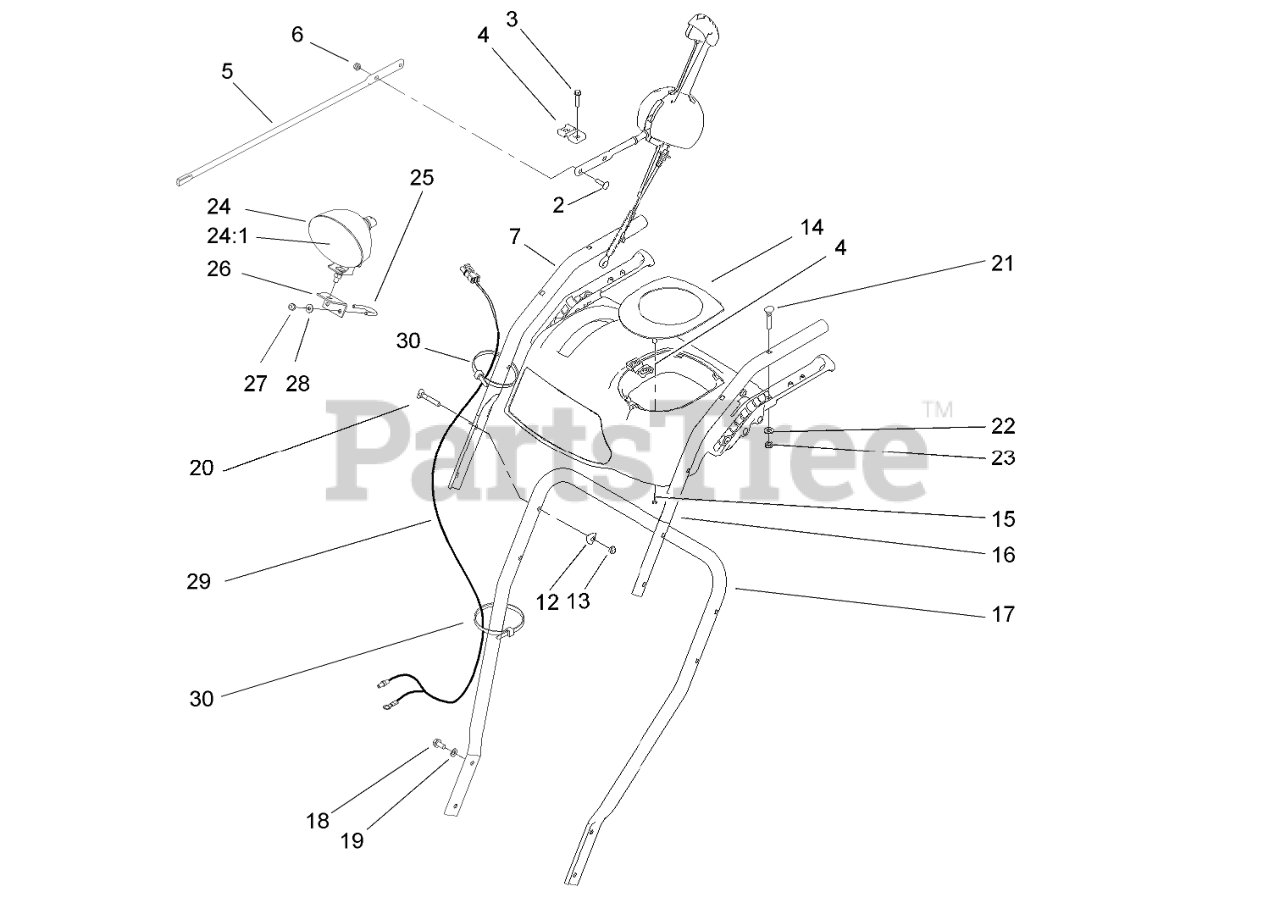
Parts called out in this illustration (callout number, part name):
2	SCREW-CARR
3	SCREW-PLASTITE
4	SUPPORT-ROD
5	ROD-CHUTE, FRONT
6	NUT-LOCK, NI
7	HANDLE-UPPER, RH
12	WASHER
13	NUT-LOCK, NI
14	COVER-PANEL, CONTROL
15	SCREW-PPH
16	HANDLE-UPPER, LH
17	HANDLE-LOWER
18	SCREW-HWHTF
19	WASHER-BELLEVILLE
20	SCREW-HANDLE
21	SCREW-HANDLE
22	WASHER-FLAT
23	NUT-LOCK, NI
24	HEADLAMP ASM
24:1	LAMP-12 VOLT
25	CLAMP
26	BRACKET-LIGHT
27	NUT-LOCK, NI
28	WASHER-FLAT
29	HARNESS-WIRE
30	TIE-CABLE
